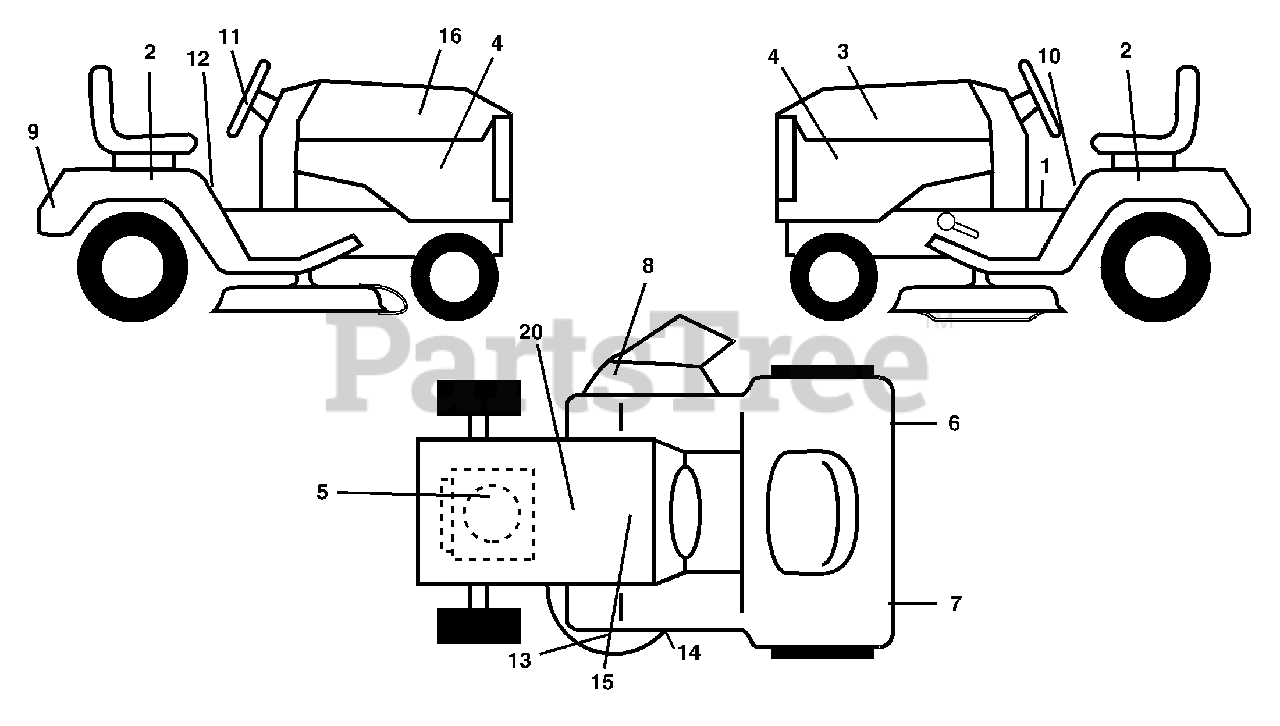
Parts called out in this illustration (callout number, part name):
1	Decal Dash
2	Decal Fender Auto
3	Decal Hood LH
4	Decal Side Panel
5	Decal HP Engine
6	Decal Reflector Rh
7	Decal Reflector Lh
8	Decal Warning Mower
9	Decal Fender Logo
10	Decal Fender Danger E/F
11	Decal Ins Strg Whl
12	Decal Fender Oper Cruise
13	Decal Deck Caution
14	Decal V-Belt Schematic
15	Decal Replace
16	Decal Hood Rh
20	Decal Bat Dan/Psn
